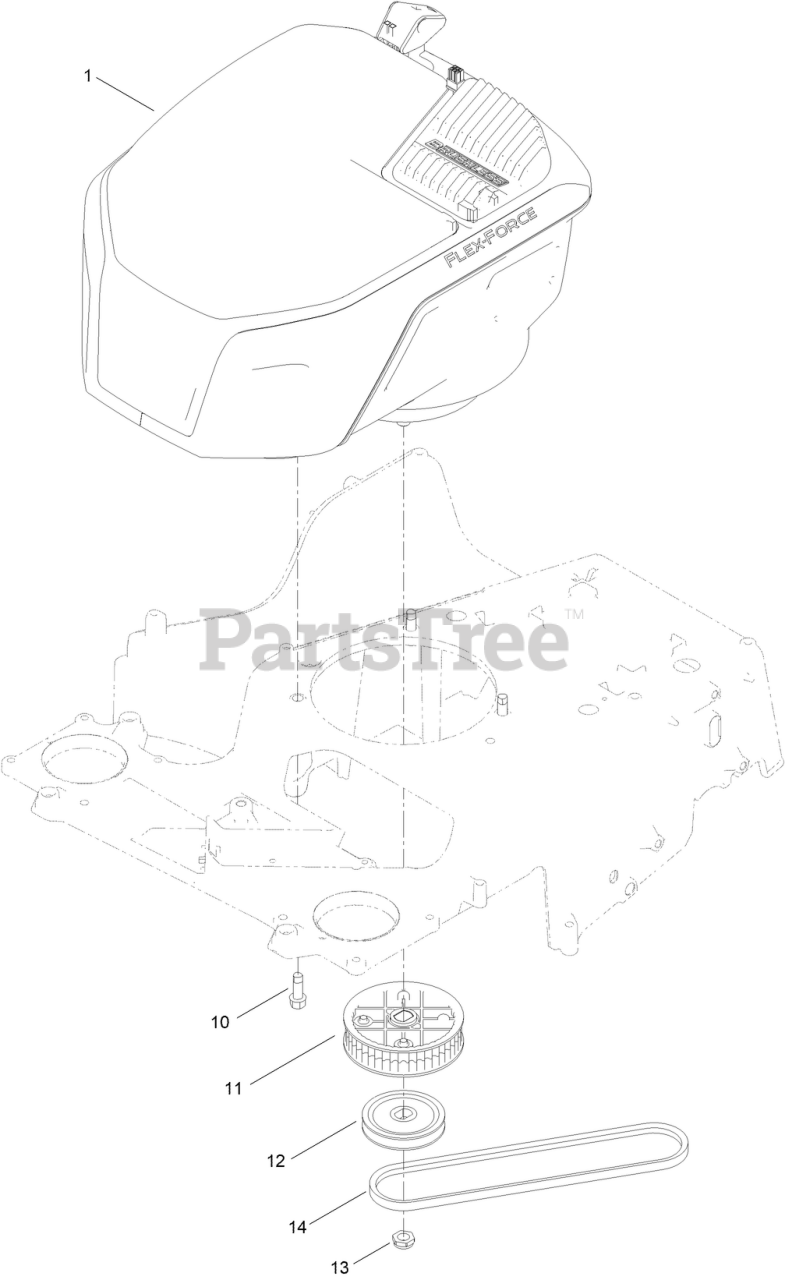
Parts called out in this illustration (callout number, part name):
1	MOTOR MODULE 60V
10	SCREW-THD FORM, HWH
11	SPROCKET
12	PULLEY-TRACTION
13	NUT-LOCK, NI
14	BELT-V
